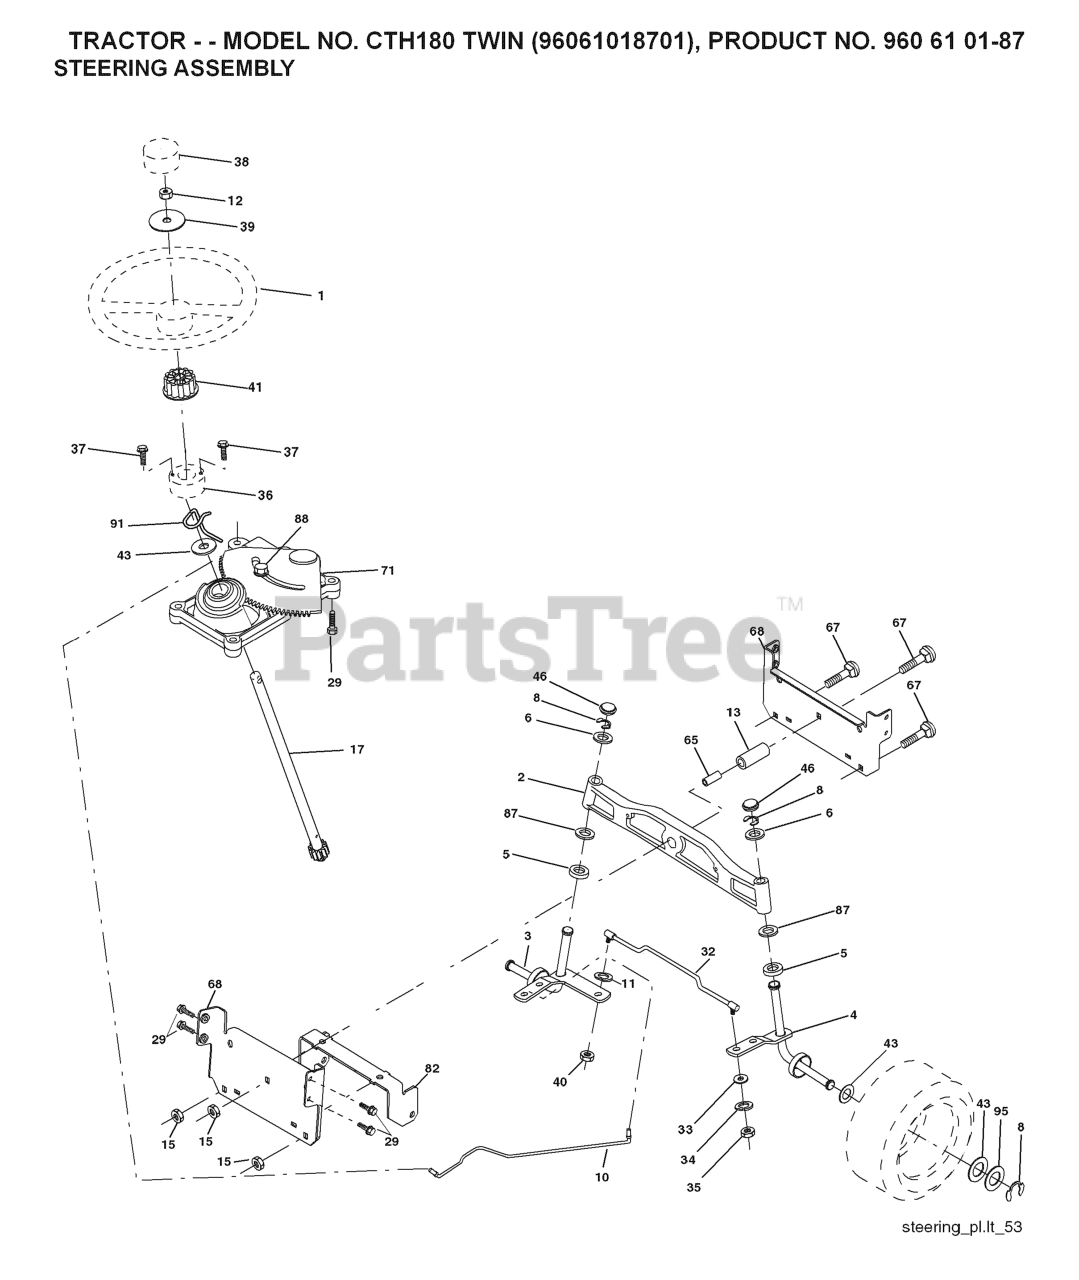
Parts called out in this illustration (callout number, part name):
1	STEERING WHEEL
2	AXLE ASSY FRONT
3	SPINDLE.ASM.LH.15"TIRES
4	SPINDLE.ASM.RH.15"TIRES
5	THRUST WASHER
10	DRAGLINK.15".TIRES.2001
11	WASHER, LOCK 3/8
12	NUT.HEX.1/2-20
13	TUBE, PIVOT AXLE
15	NUT
17	SHAFT ASM STRG
29	SCREW, 3/8-16X3/4
33	WASHER M
34	WASHER.LOCK.HVY.HLCL.SPR.5/16
35	NUT, CROWNLOCK
36	BUSHING, STRG. BLK
37	SCREW.TT.#10-32X.5.3/8.FLANGE
38	INSERT.CAP.STRG.WH.GRAY
39	WASHER 9/16"ID, 2 3/8"OD
40	NUT CROWNLOCK 3/8-24
41	ADAPTER, WHEEL STNG..
46	CAP.SPINDLE.BLACK
65	SPACER BRACE AXLE
67	BOLT CARRIAGE
68	BRACE.AXLE.15"TIRES
71	STEERING ASM
82	BRACKET.SUSP.CHASSIS.FRONT.15
87	WASHER, FLAT .781 X 1 1/2"
88	BOLT, SHOULDER 7/16-20
91	CLIP.STEERING
95	WASHER.HARDENED
